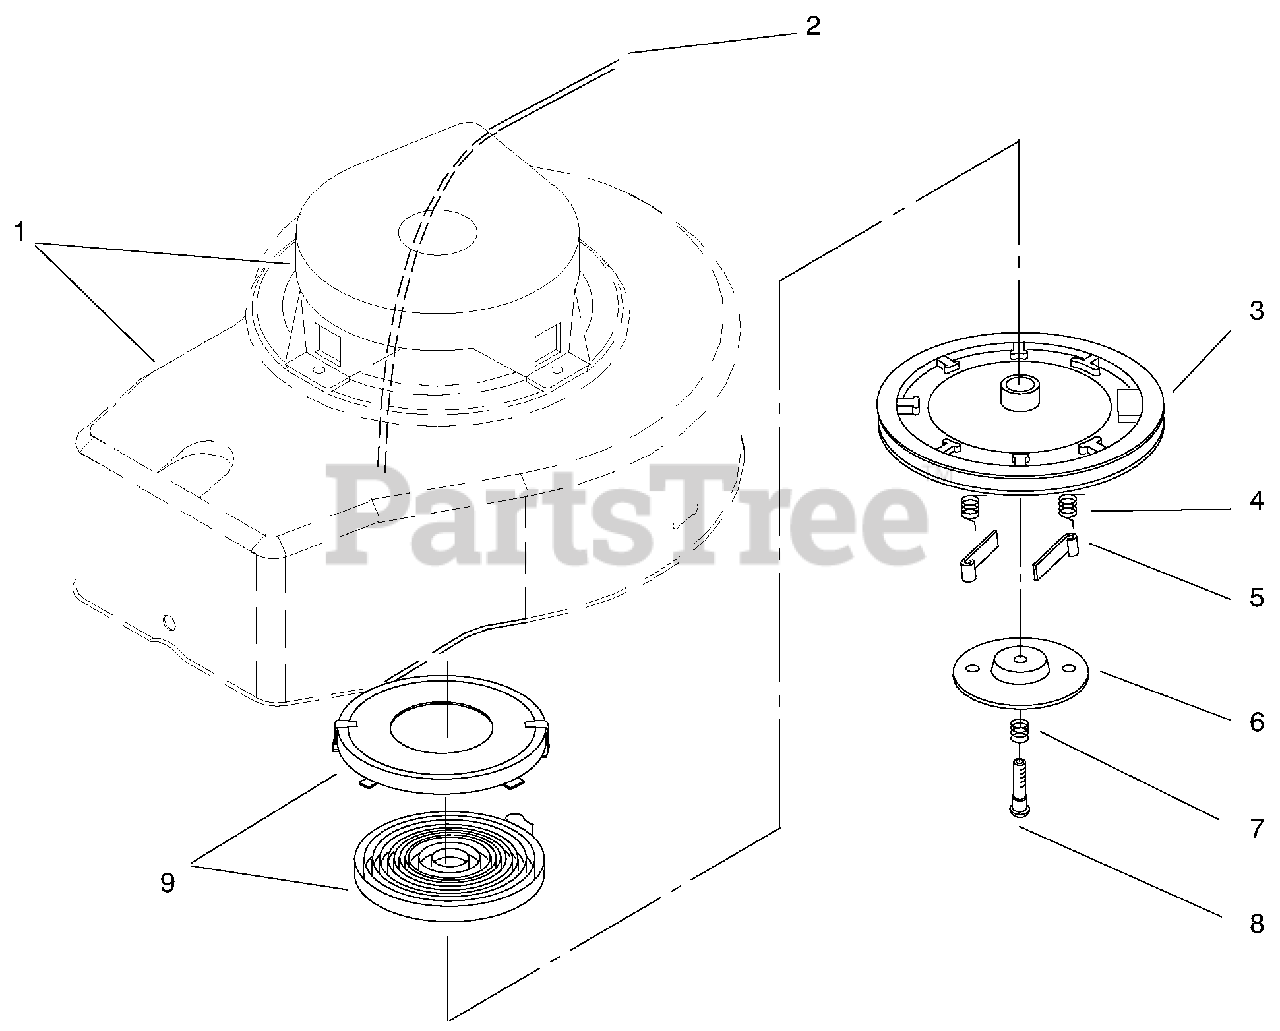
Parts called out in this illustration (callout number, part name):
1	SHROUD
2	ROPE - GREY 88 5/8
3	PULLEY ASSEMBLY
4	SPRING - DOG
6	RETAINER
7	SCREW - CENTER
8	SPRING - BRAKE
9	SPRING KEEPER ASM
